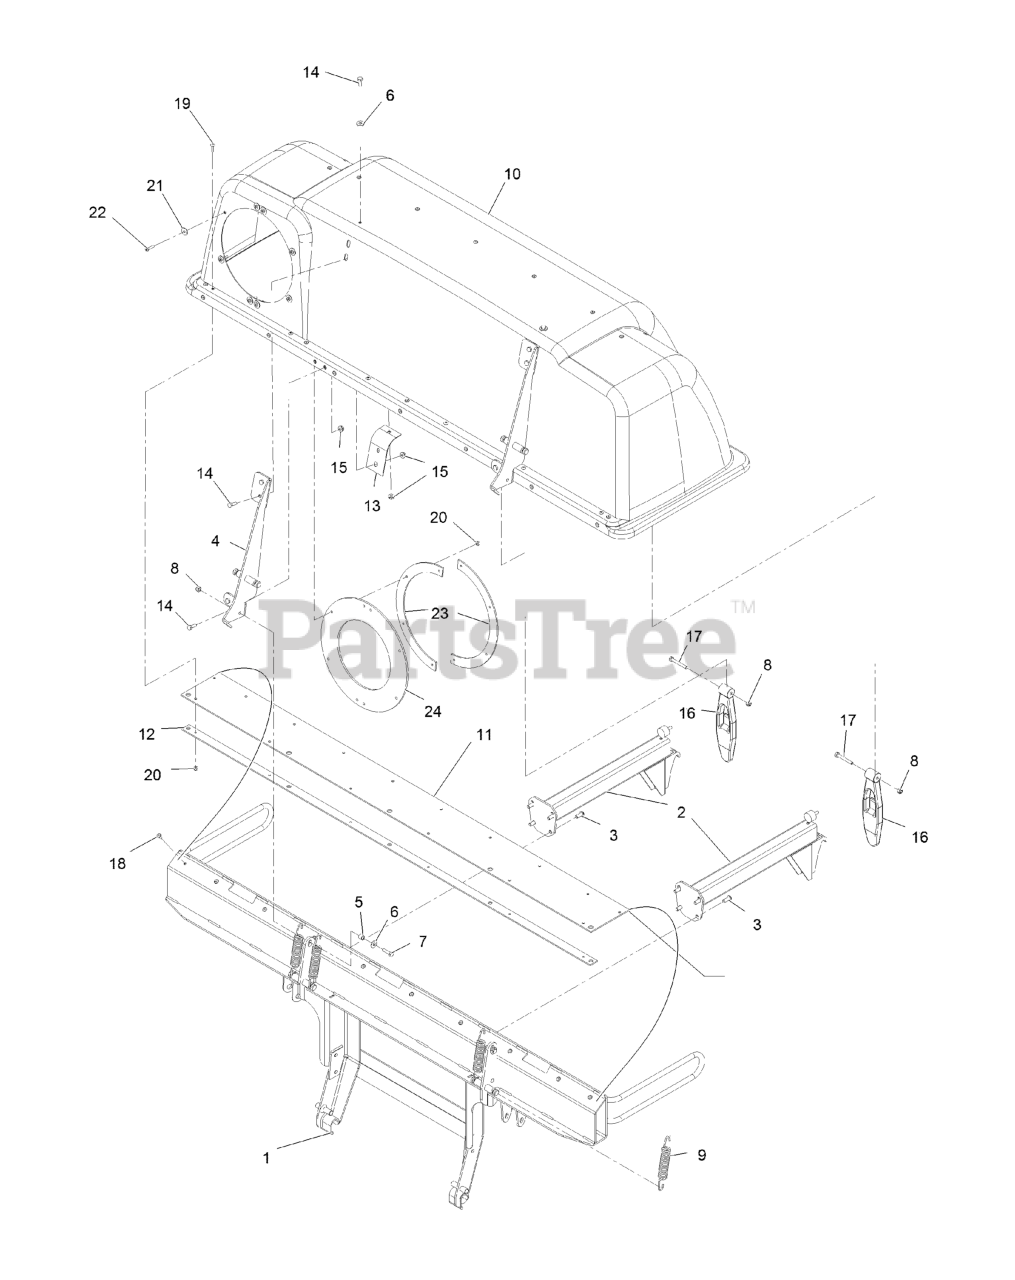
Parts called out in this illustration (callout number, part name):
1	FRAME-3-BAG
2	BAG SUPPORT ASM
3	SCREW-HSBH
6	WASHER-FLAT
7	SCREW-HH
8	NUT-LOCK, NI
9	SPRING-EXTENSION
10	ASM, HOOD
11	SEAL-HINGE
12	PLATE-BACKING
13	REINFORCEMENT-HOOD, BAGGE
14	SCREW-HH
17	SCREW-HH
18	RIVET-BLIND
19	SCREW-HEAD, TRUSS
20	NUT-LOCK, NI
21	WASHER-FLAT
22	SCREW-PPH
23	CLAMP-SEAL
24	SEAL-TUBE
